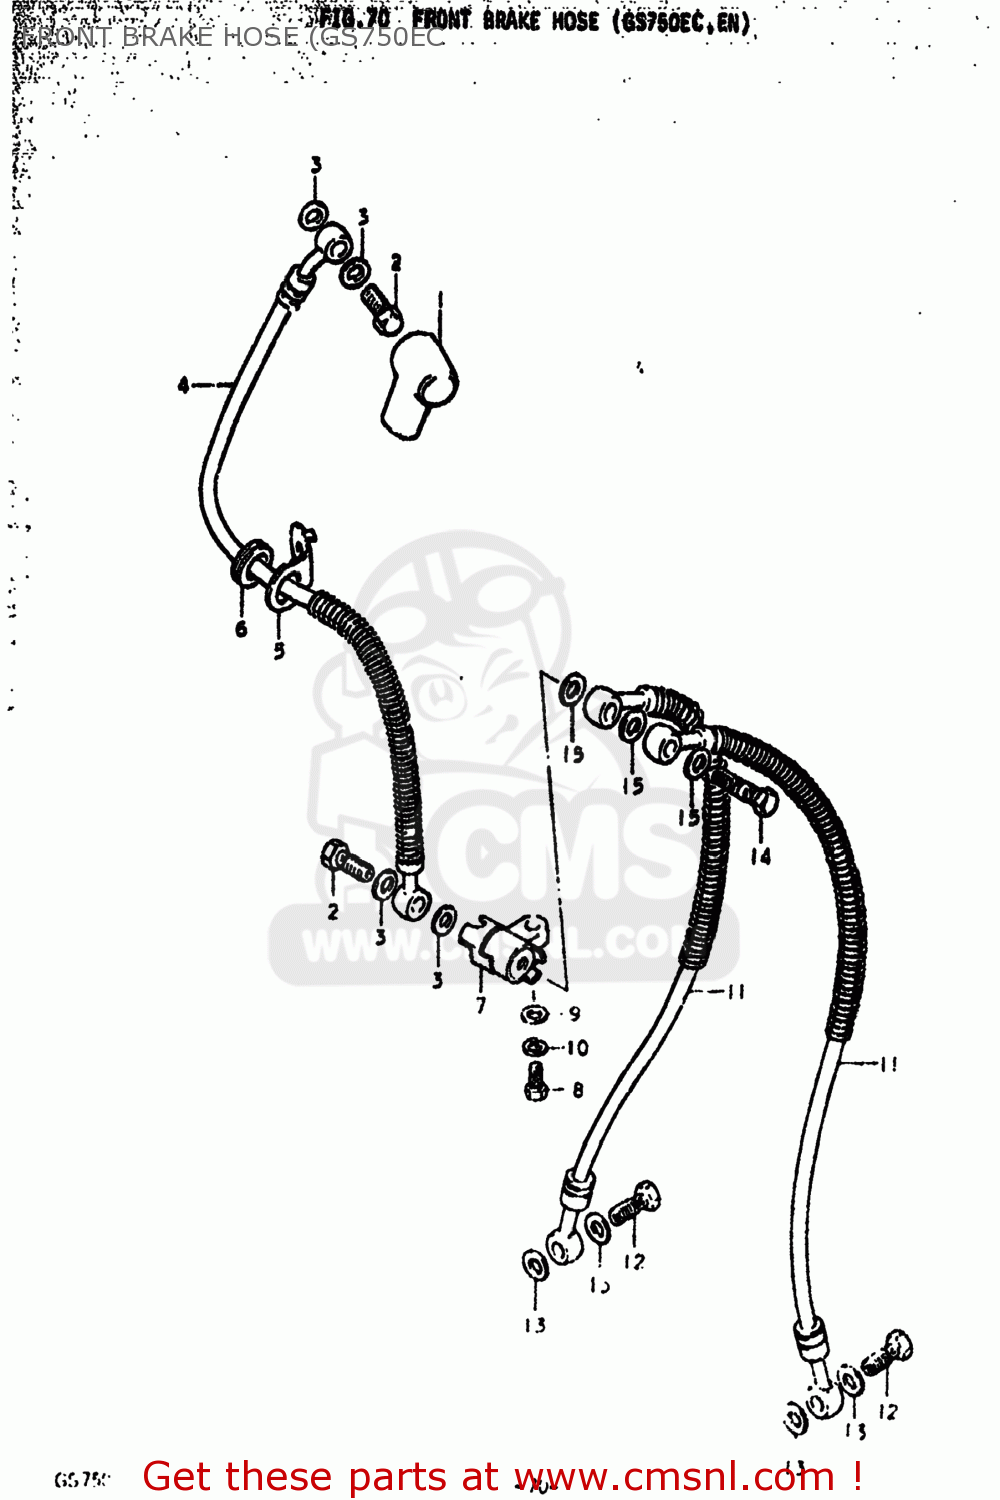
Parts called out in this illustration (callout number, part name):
1	BOOT,MASTER CYLINDER
2	BOLT UNION
3	WASHER
4	HOSE,BRAKE NO.1
5	GUIDE,BRAKE HOSE
6	GROMMET
7	JOINT,BRAKE HOSE
8	BOLT
9	WASHER
10	LOCK WASHER
11	HOSE,FRONT BRAKE
12	BOLT UNION
13	WASHER
14	BOLT UNION
15	WASHER
